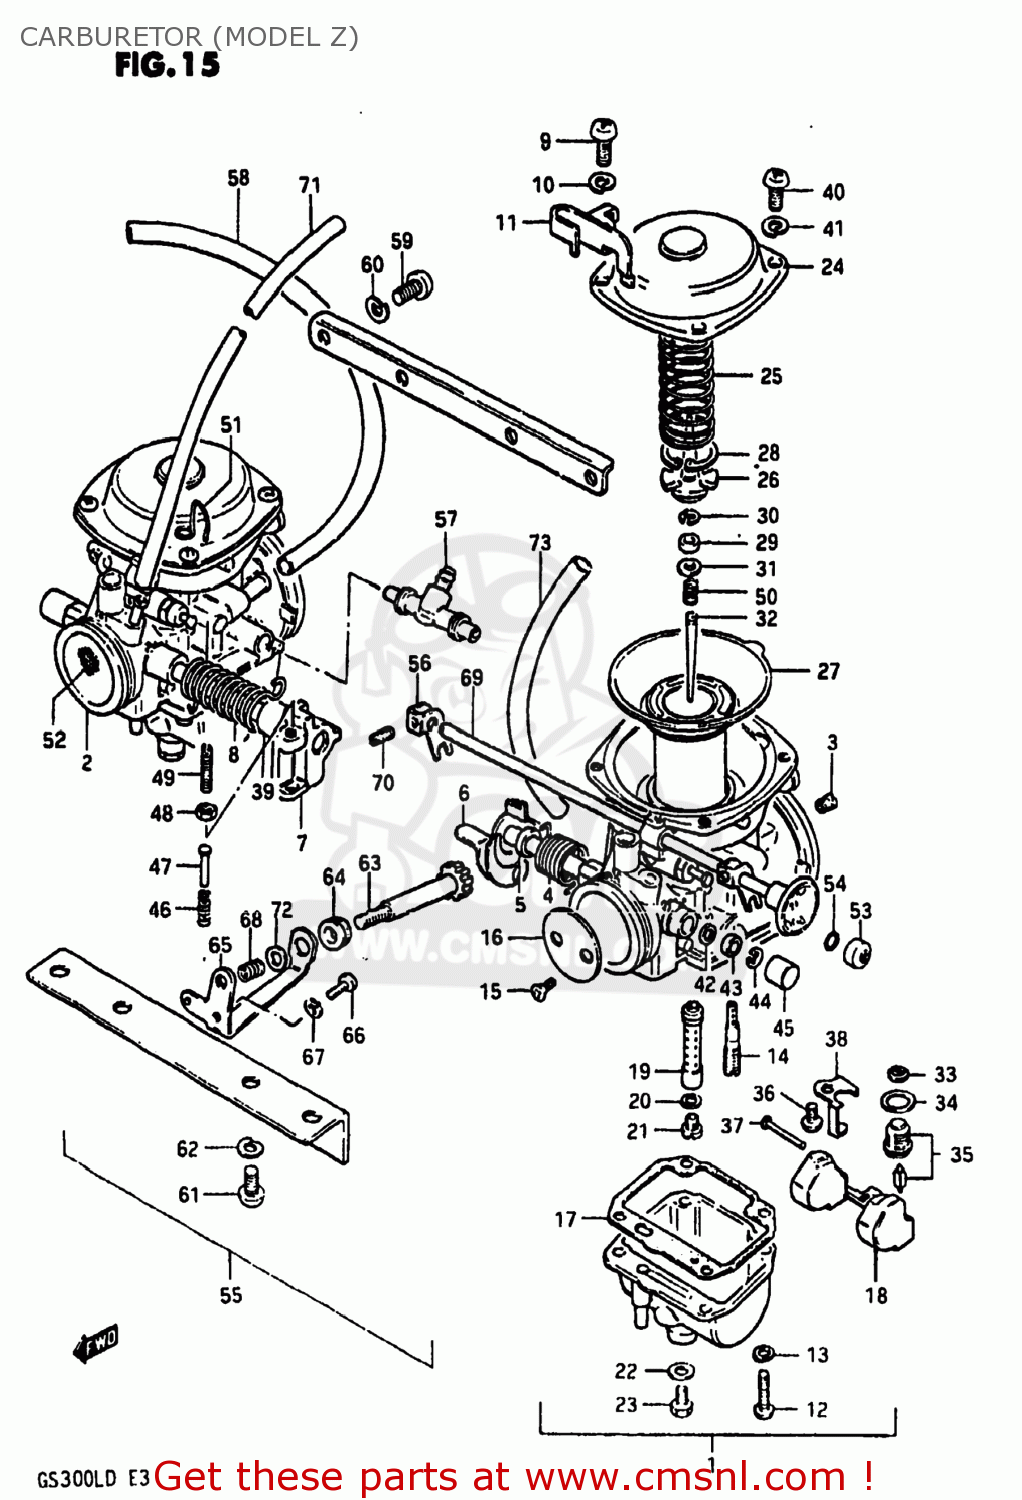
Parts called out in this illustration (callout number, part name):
1	CARBURETOR ASSEMBLY
2	CARBURETOR ASSEMBLY,RIGHT (BS
3	JET,MAIN
4	SPRING
5	RING
6	SHAFT ASSEMBLY
7	SHAFT ASSEMBLY
8	SPRING
9	SCREW
10	LOCK WASHER
11	BRACKET
12	SCREW
13	LOCK WASHER
14	JET,PILOT(17.5)
15	SCREW
16	VALVE,THROTTLE
17	GASKET,FLOAT CAHMBER (NAS)
18	FLOAT
19	JET,NEEDLE
20	WASHER,NEEDLE NOZZLE
21	JET,MAIN(115)
22	GASKET (NAS)
23	PLUG,DRAIN
24	COVER,DIAPHRAGM
25	SPRING
26	HOLDER,GUIDE
27	DIAPHRAGM
28	E RING
29	RING
30	CLIP,NEEDLE
31	WASHER
32	NEEDLE JET
33	FILTER
34	O RING
35	VALVE ASSEMBLY,NEEDLE
36	SCREW 4X6
37	PIN,FLOAT
38	PLATE,NEEDLE VALVE FITING
39	RING,THROTTLE VALVE
40	SCREW
41	LOCK WASHER
42	SEAL
43	GASKET,THROTTLE SHAFT (NAS)
44	E RING
45	CAP
46	SPRING,THROTTLE SCREW
47	PIN,THROTTLE LEVER
48	NUT
49	SCREW
50	SPRING
51	CLIP,HOSE
52	FILTER NET ASSEMBLY
53	CAP,PLUNGER
54	O-RING
55	CARBURETOR ASSEMBLY
56	LEVER
57	NIPPLE,CARBURETOR
58	HOSE
59	SCREW
60	LOCK WASHER
61	SCREW
62	LOCK WASHER
63	SCREW,THROTTLE STOP
64	BUSHING,THROTTLE ADJUSTER
65	BRACKET,THROTTLE ADJUST
66	SCREW
67	LOCK WASHER
68	SPRING
69	SHAFT,STARTER
70	SCREW
71	HOSE
72	WASHER
73	HOSE
